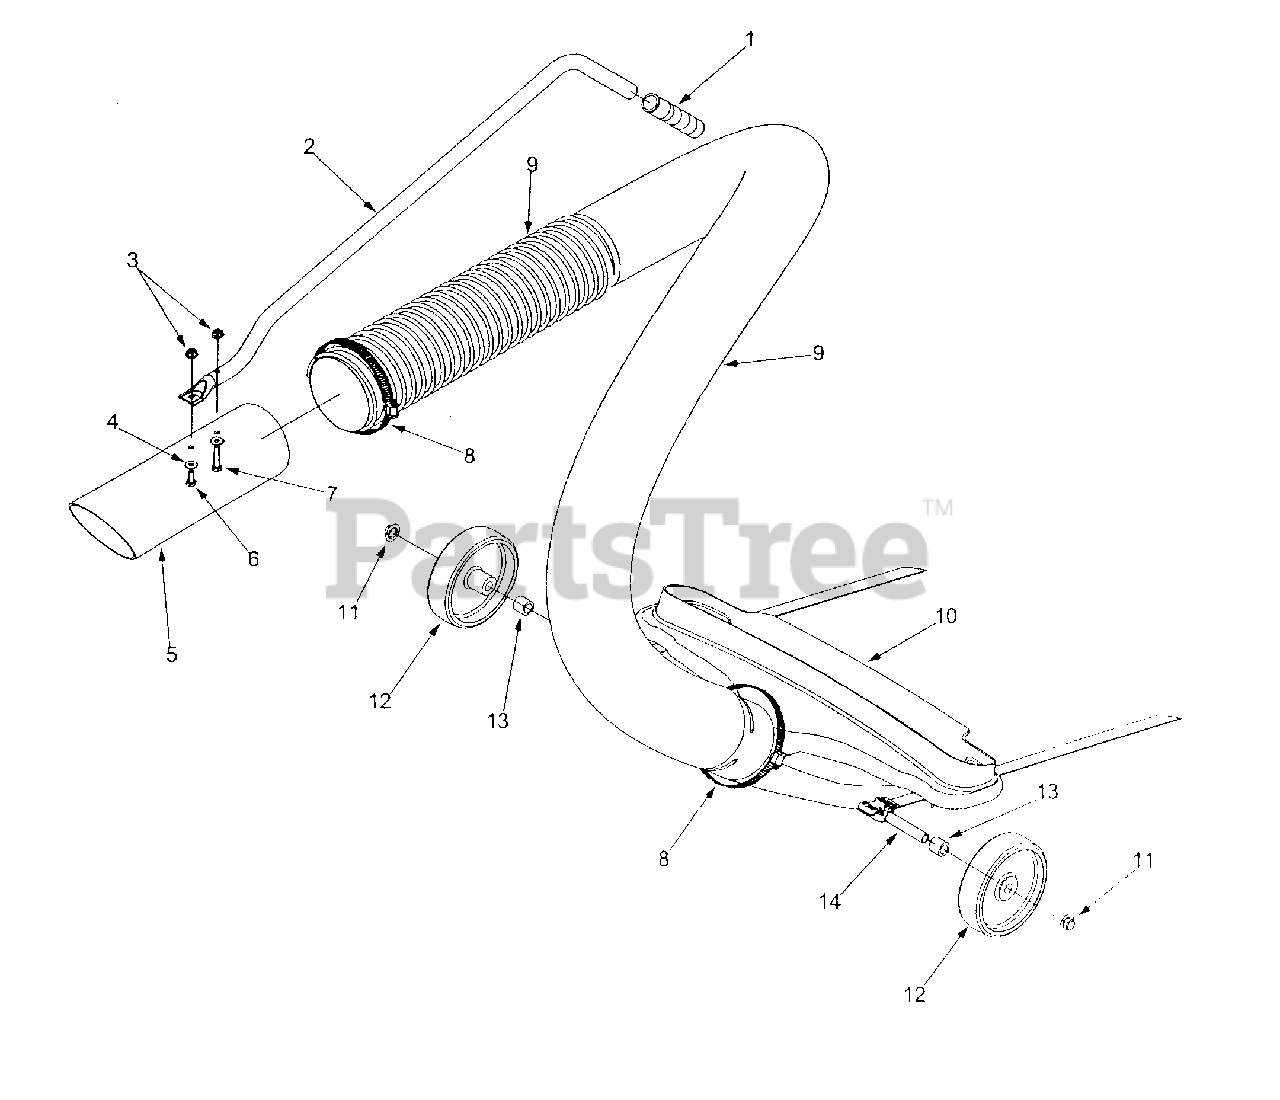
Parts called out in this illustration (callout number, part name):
1	Handle Grip
3	Hex Lock Nut 1/4-20
4	Flat Washer .271 ID x .630 OD
5	Nozzle 3.875 x 12.0
6	Hex Cap Screw 1/4-20 x .620
7	Hex Cap Screw 1/4-20 x 1.25
8	Adjustable Clamp
10	Hose Attachment Nozzle Ass'y
12	Wheel 5.0 x 1.38
14	Axle .50 OD x .354 ID x 16.7
